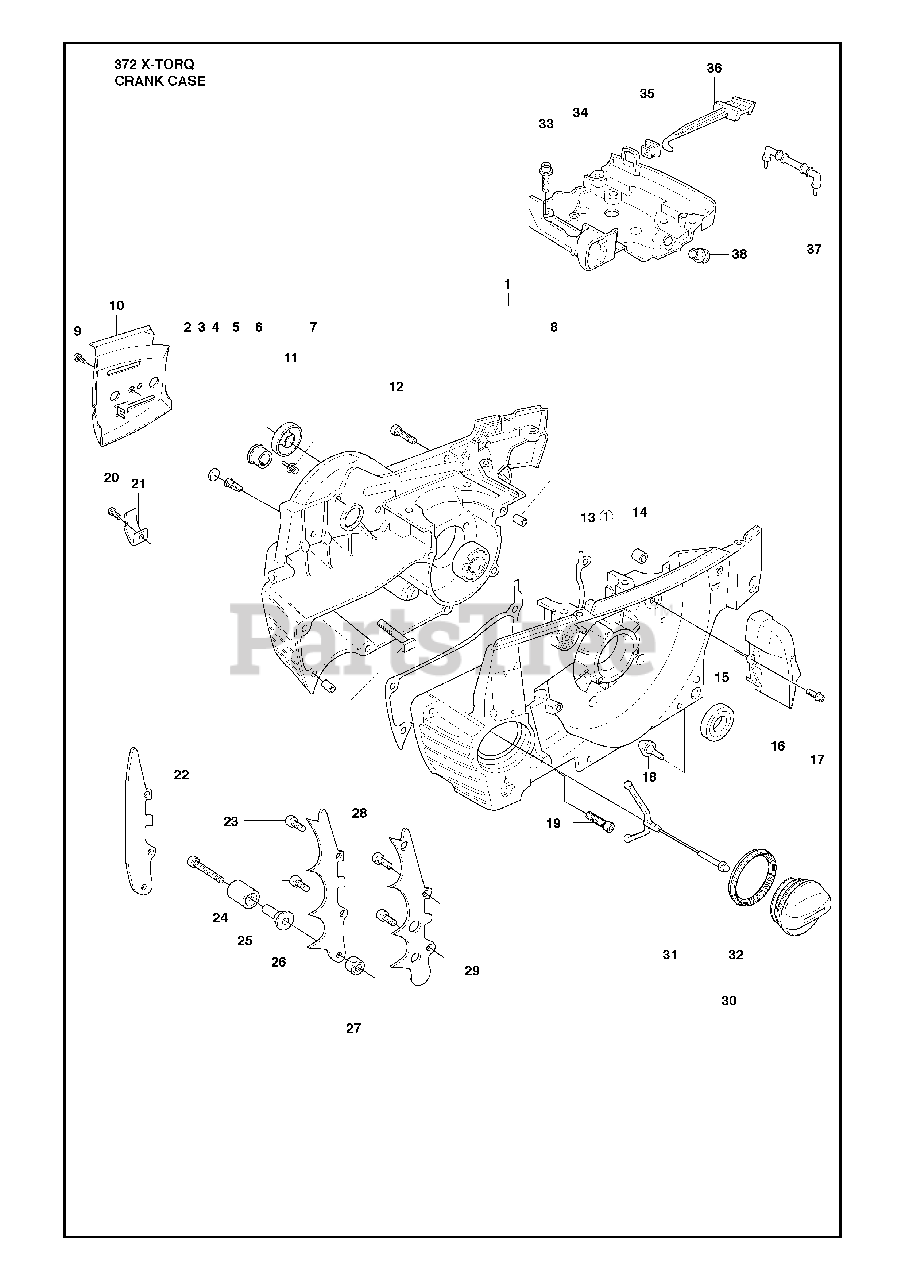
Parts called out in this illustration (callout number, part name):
1	RP CRANKCASE
4	VALVE-CHECK (DUCKBILL)
5	PLUG
20	SCREW MC6S 5X20
21	CHAIN CATCHER
26	CHAIN CATCHER
28	FELLING DOG
29	FELLING DOG
30	TANK CAP
34	BASE
37	SPACER
